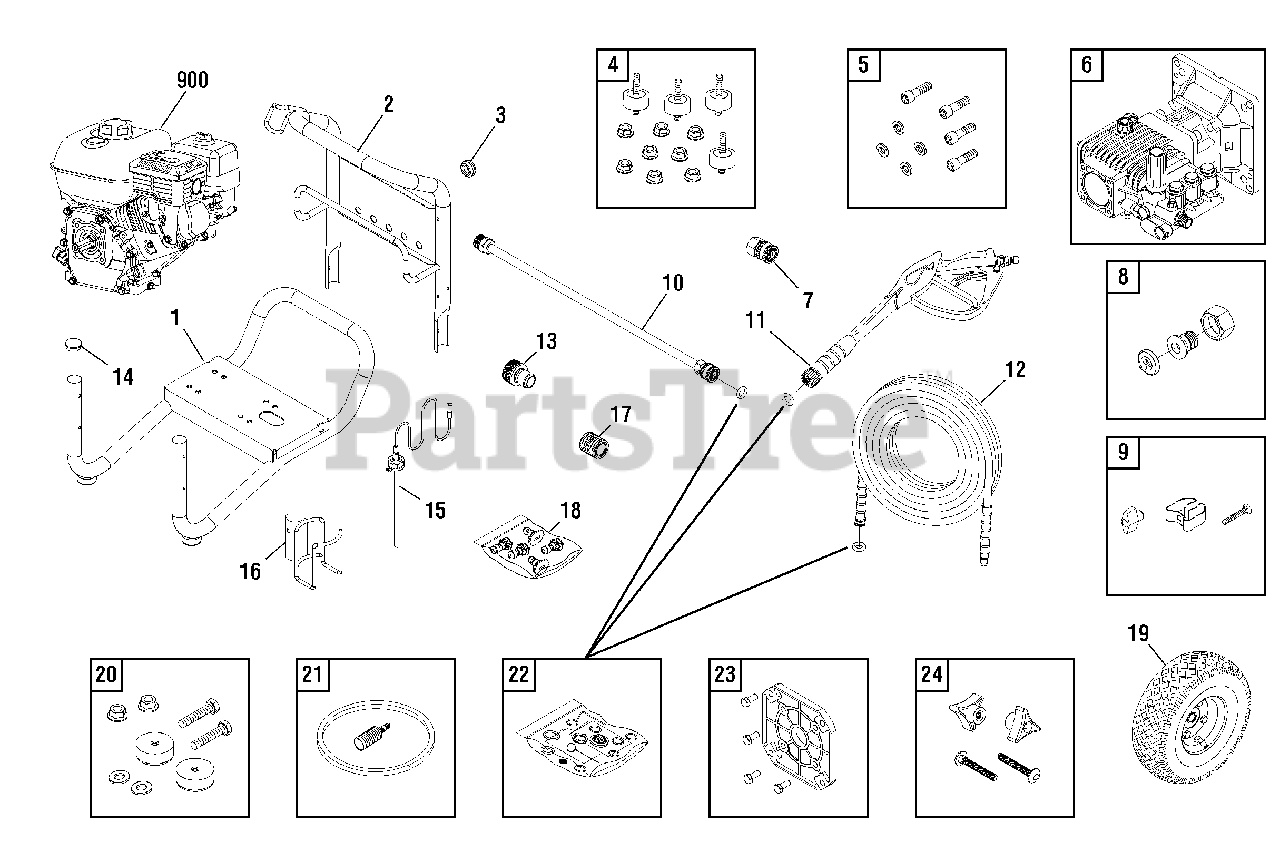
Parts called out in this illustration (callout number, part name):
1	BASE
4	KIT-VIBRATION MOUNT
5	KIT-HARDWARE PUMP MOUNTING
7	ADAPTER
8	ADAPTER-GARDEN HOSE
10	EXTENSION-QC
18	KIT-QC NOZZLES
20	MOUNT-VIBRATION
23	FLANGE-ENGINE
24	KIT-HARDWARE HANDLE
900	** ENGINE
